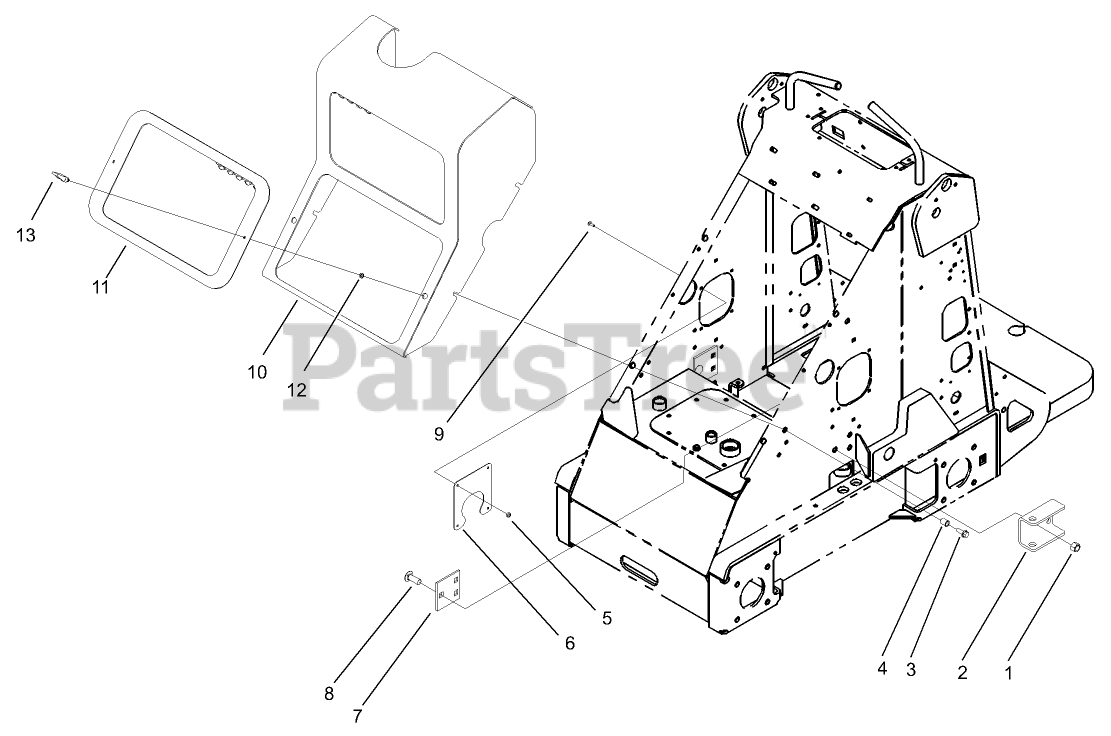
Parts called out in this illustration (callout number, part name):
1	NUT-LOCK, NI
2	BRACKET-ANCHOR
3	SCREW-HHF
4	INSERT-THREADED
5	NUT-LOCK, NI
6	GUARD-MUFFLER
7	PLATE-ANCHOR
8	SCREW-CARR, SHORT NECK
9	SCREW-CARR
12	WASHER
13	LATCH-SWELL
